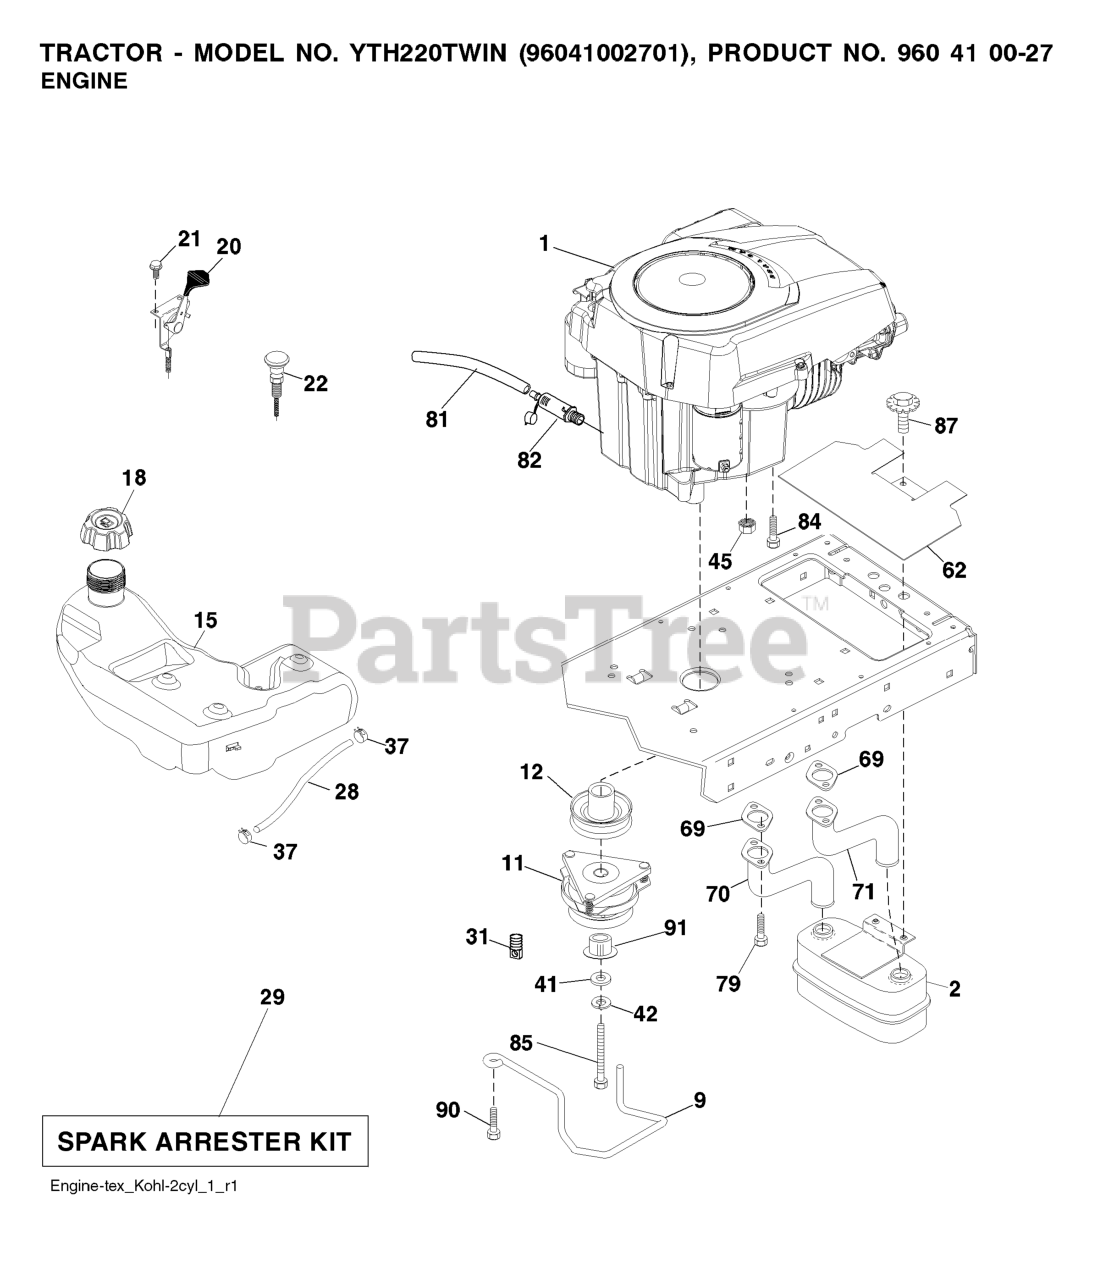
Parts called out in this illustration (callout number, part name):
2	MUFFLER.TWIN.CYL.LOW.TONE
9	KEEPER.BELT.ENGINE.3.25 (3 2)
11	CLUTCH MZ ZTR GT.48/54"1.125"
12	PULLEY ENGINE
15	TANK.FUEL.4GAL
18	CAP.FUEL.TANK.3"GREY
20	THROTTLE CONTROL
21	SCREW
22	CONTROL.CHOKE.ERGO.PUSH-IN.BLA
28	REPL BY 532 00 85-43
29	KIT.SPARK ARRESTOR 794945 B&S
37	HOSE CLAMP
42	LOCKWASHER
45	NUT
62	RP SHIELD HEAT MUFFLER
70	RP.PIPE-EXHAUST LH
71	RP.PIPE-EXHAUST RH
79	SCREW.SOCKET HD.5/16-1
81	TUBE, DRAIN OIL ASM.
82	PLUG DRAIN OIL EASY
83	BOLT.5/16-18UNCX3/4 W/SEMS.BLK
84	SCREW 3/8-16X1
85	BOLT HEX 7/16-20 X 3.75 GR. 5
90	SCREW 3/8-16X1
91	BUSHING.1.375OD
102	SCREW
105	SHIELD SIDE
106	SHIELD SIDE
107	SCREW.1/4-20X5/8
